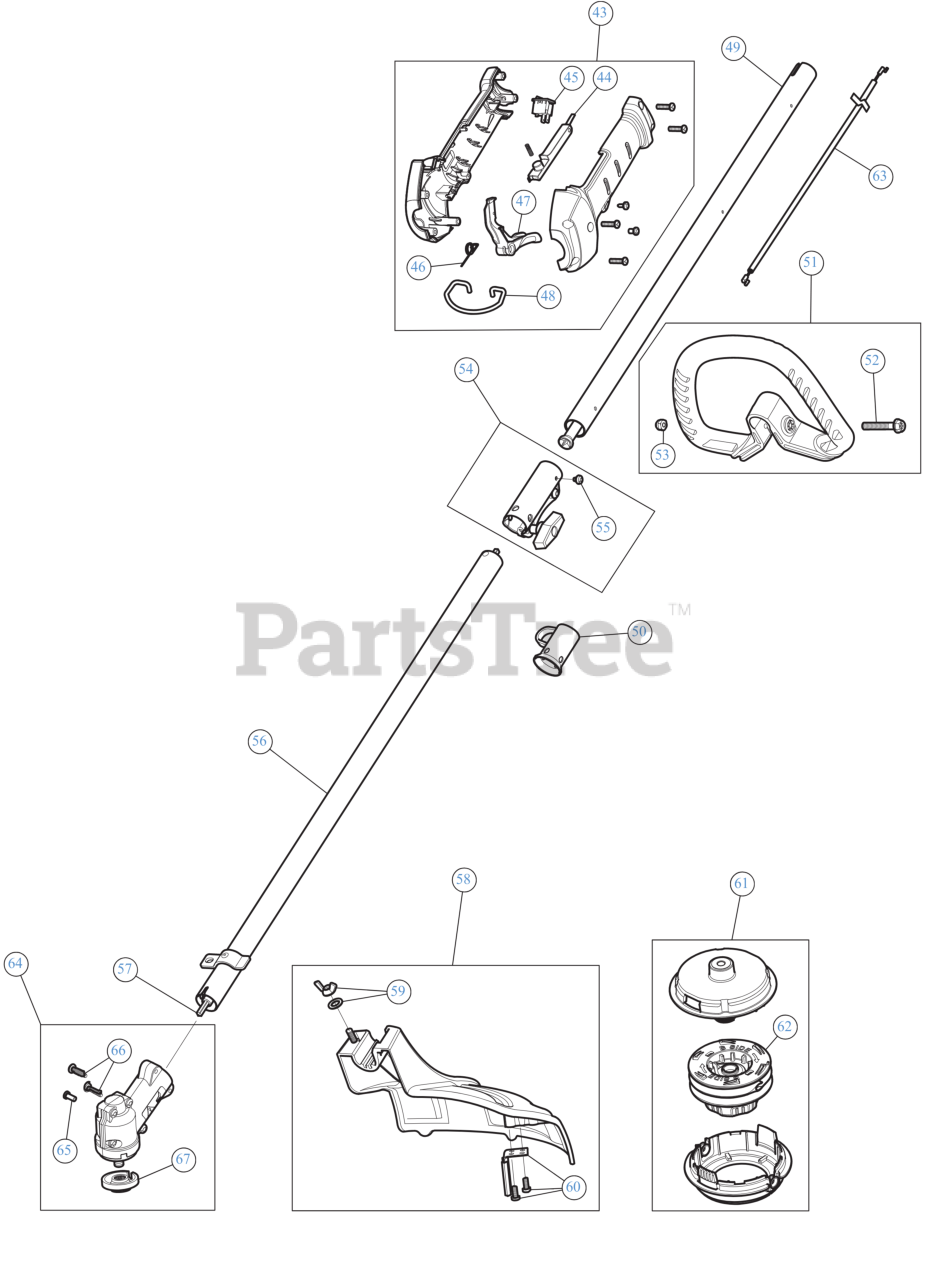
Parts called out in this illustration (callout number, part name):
43	THROTTLE GRIP ASM
44	LEVER LOCK OUT
45	SW, MOMENTARY ON/O
46	TRIGGER SPRING
47	THROTTLE TRIGGER
48	SHOULDER STRAP CLIP
49	UPPER SHAFT HOUSING
50	HANGER
51	HANDLE DLX
52	BOLT 1/4-20X1 1/2
53	NUT 1/4-20 NYLOC
54	COUPLER ASSEMBLY
55	SCREW, 10-32X.250 TA
56	LOWER SHAFT HOUSING
57	LOWER DRIVE SHAFT
58	GUARD/BLADE ASM
59	BLADE GUARD MOUNTING HARDWARE
60	BLADE ASSEMBLY W/HDW
61	CUTTING HEAD
62	BUMP KNOB
63	THROTTLE CABLE
64	GEARBOX LCBC
65	SCREW, 8-32 x .312 P
66	SCREW #
67	CUTTING HEAD SPACER
